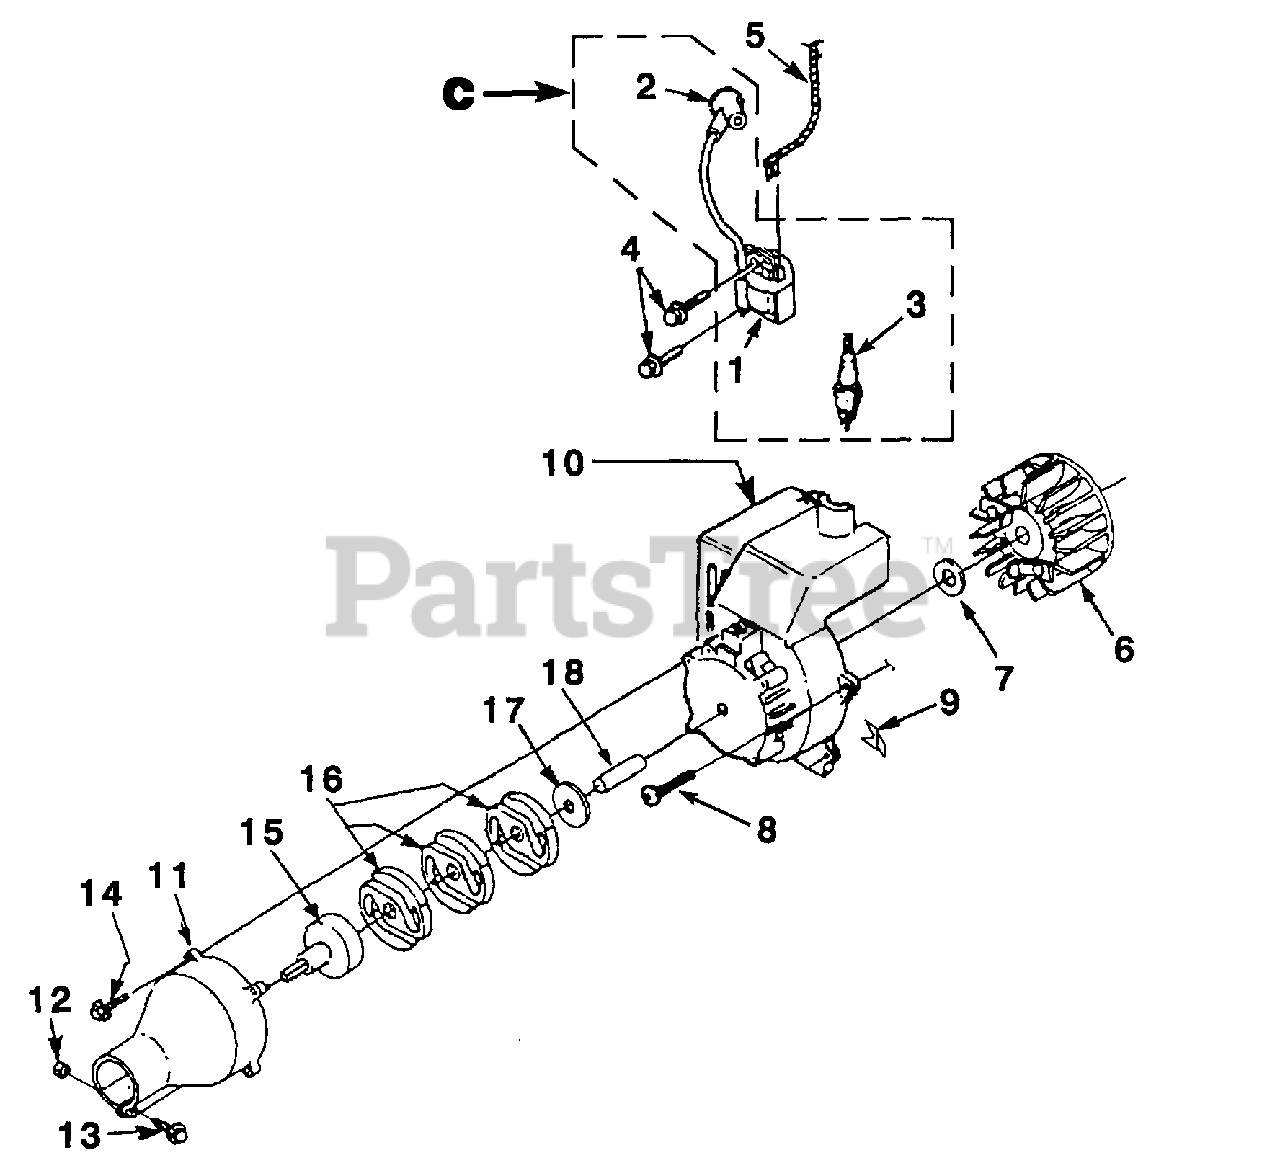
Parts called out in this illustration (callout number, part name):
1	MODULE-Ignition
2	TERMINAL & COVER
3	SPARK PLUG (RDJ-7Y)
4	SCREW-Thread Form. (8-32 x 1")
5	LEAD-Electrical
6	ROTOR & STARTER PAWL
7	WASHER-Flat
8	SCREW-Thread Form. (10-24 x 3/4")
9	TAB-Male
10	HOUSING-Engine w/Decals
11	TUBE ADAPTOR KIT
12	NUT-Hex (10-24)
13	SCREW-Sems Hex Hd. (10-24 x 1 1/4")
14	SCREW-Sems Hex Hd. (10-24 x 7/8")
15	DRUM & CONNECTOR
17	WASHER-Clutch
18	SPACER
